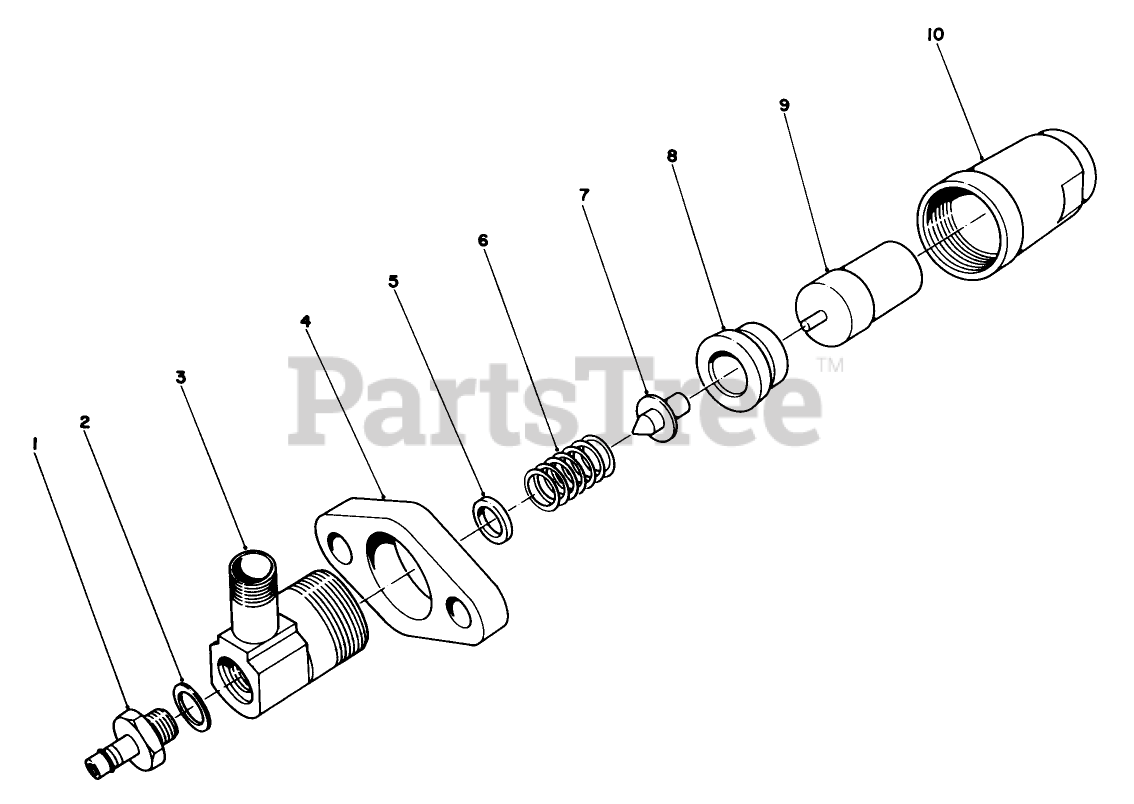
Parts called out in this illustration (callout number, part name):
1	Nipple
2	Washer
3	Body
4	FLANGE
5	WASHER
6	Spring Pressure
7	PRESSURE PIN MM500135
8	Piece-Distance
9	NOZZLE ASM
10	RET NUT
